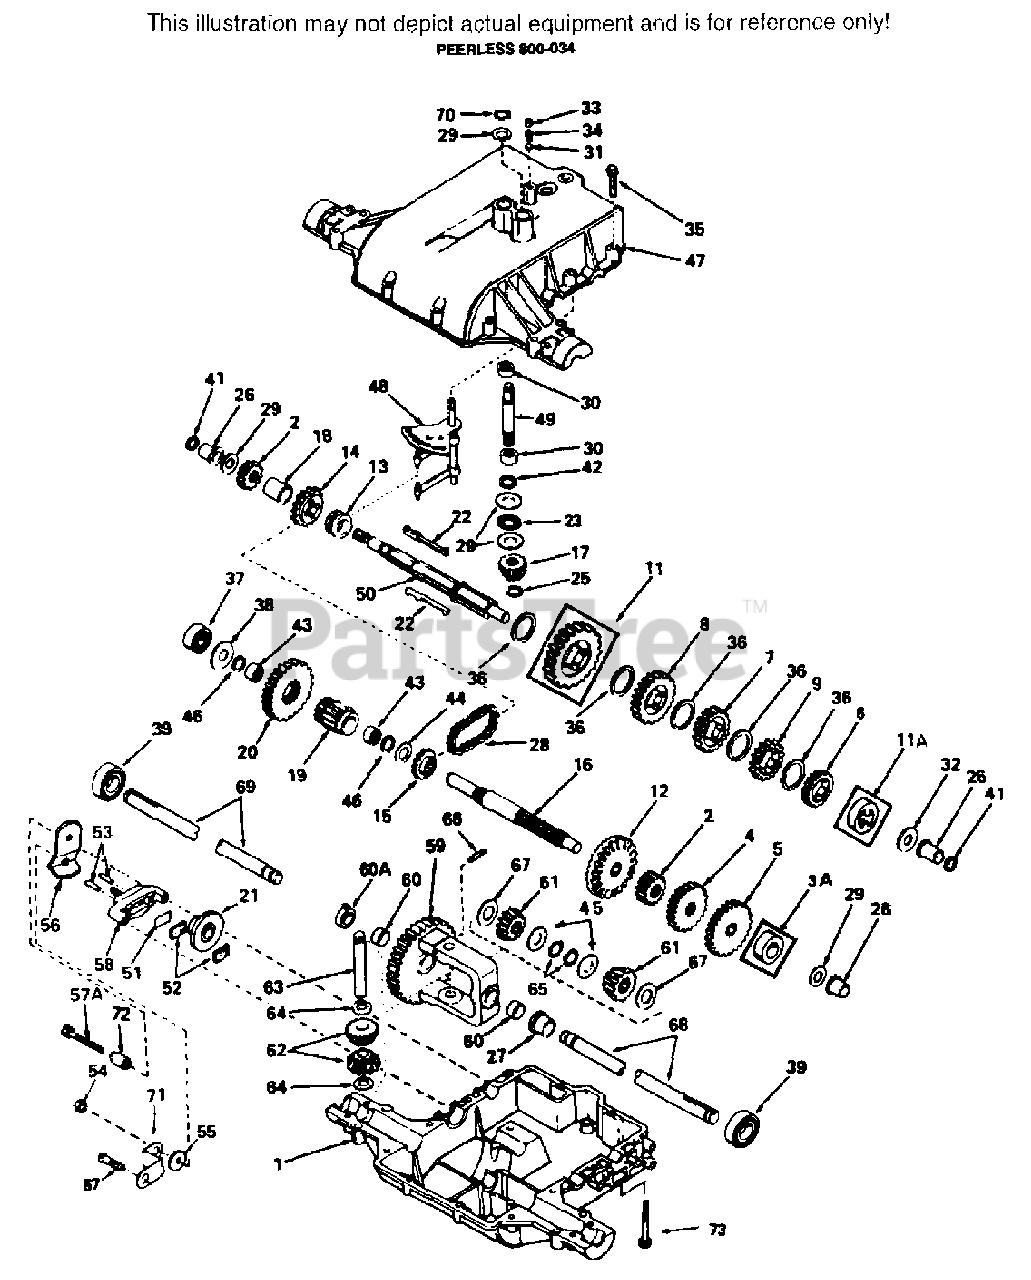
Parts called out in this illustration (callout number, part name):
1	CASE, TRANSAXLE
2	GEAR, SPUR(15 TEETH)
3A	SPACER
4	GEAR, SPUR(20 TEETH)
5	GEAR, SPUR(28 TEETH)
6	GEAR, SPUR(22 TEETH)
7	GEAR, SPUR(30 TEETH)
8	GEAR, SPUR(35 TEETH)
9	GEAR, SPUR(25 TEETH)
11	GEAR, SPUR(37 TEETH)
11A	SPACER
12	GEAR, BEVEL(42 TEETH)
13	COLLAR, SHIFT
14	SPROCKET(18 TEETH)
15	SPROCKET(9 TEETH)
16	SHAFT, COUNTER
17	BEVEL PINION, INPUT
18	SPACER
19	PINION, OUTPUT
20	GEAR, OUTPUT
21	DISC, BRAKE
23	BEARING, THRUST
25	RING, RETAINING
26	BUSHING, FLANGED
27	BUSHING, FLANGED
28	CHAIN, ROLLER(NO. 41 CHAIN, 24 LINKS)
29	WASHER, THRUST
30	BEARING, NEEDLE
31	BALL, STEEL
32	WASHER, THRUST
33	SCREW, SET, 3/8-16 X 3/8
34	SPRING
35	SCREW, HEX HD. THRD. FRM, 1/4-20 X 1-1/4
36	WASHER, THRUST
37	BEARING, BALL
38	WASHER, FLAT
39	BEARING, BALL
41	RING, SQUARE CUT
42	RING, SQUARE CUT
43	BEARING, NEEDLE
44	WASHER, FLAT
46	RING, SQUARE CUT
47	COVER, TRANSAXLE
48	ROD & FORK ASSEMBLY, SHIFT
49	SHAFT, INPUT
50	SHAFT BRAKE
51	PLATE, BRAKE PAD
52	PAD, BRAKE
53	PIN, DOWEL
54	LOCKNUT, 5/16-24
55	WASHER, FLAT
56	LEVER, BRAKE
57	SCREW, HEX HD. THRD. FRM, 1/4-20 X 1-1/4
57A	SCREW, HEX HD. THRD. FRM. 1/4-20 X 2-1/4
58	HOLDER, BRAKE PAD
59	GEAR ASSEMBLY, DIFF(INCL. 2 OF NO. 60)
60	BUSHING
60A	BUSHING
61	GEAR, BEVEL
62	PINION, BEVEL
63	PIN, DRIVE
64	WASHER, THRUST
65	RING, RETAINING
66	PIN, ROLL
67	WASHER, THRUST
68	AXLE(22-5/8" LONG)
69	AXLE(12-7/8" LONG)
70	RING, RETAINING
71	BRACKET, BRAKE LEVER
72	SPACER
73	SPECIAL BOLT
